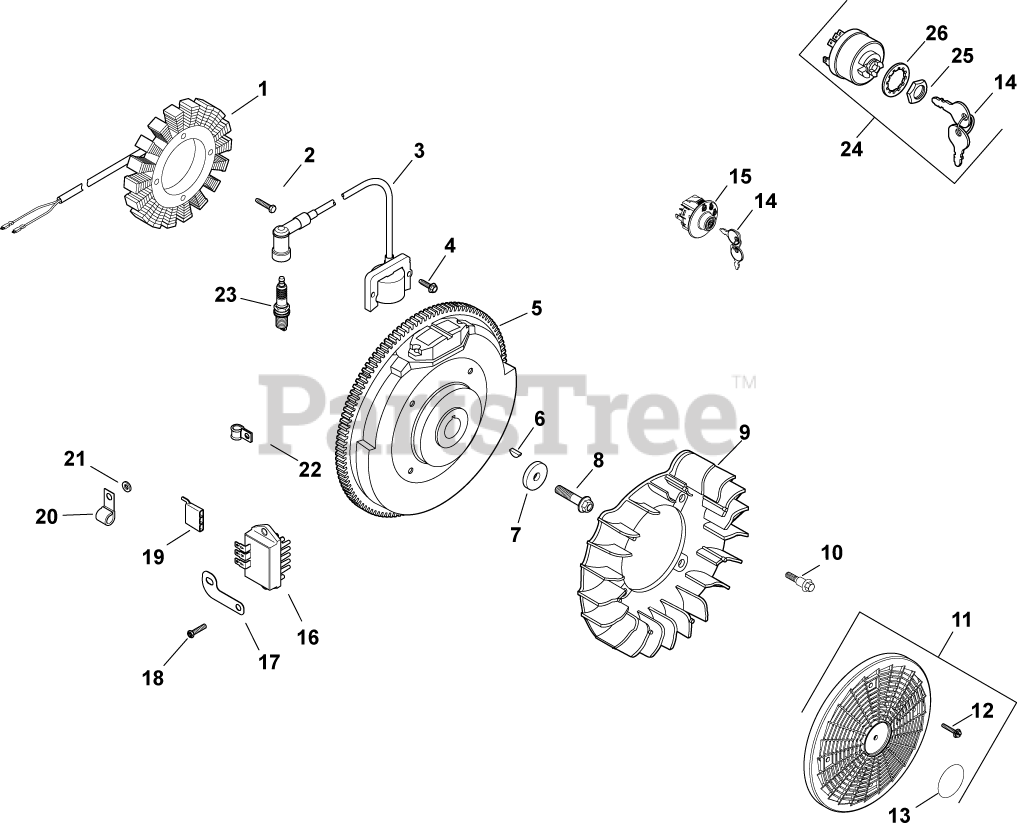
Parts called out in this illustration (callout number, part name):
1	KIT, 15 / 20 AMP STATOR
2	SCREW, THD FROM M5X0.8X30
3	KIT, MODULE IGNTN (CDI FIXED)
4	SCREW, FLG THD FRM M5X.8X20-(#25086399S)
5	FLYWHEEL ASSEMBLY
6	KEY, 3/16" X 5/8"
7	WASHER, FLAT 13/32"
8	SCREW, FLG M10X1.5X45 - (#25086361S)
9	FAN USE 24 755 253-S
10	BOLT, SHOULDER
11	KIT, GRASS SCREEN
12	SCREW, FLG SEMS M4X.7X25
13	DECAL, GRASS SCREEN USE 24 113 499-S
14	KEY, SET OF 2
15	KIT, KEY SWITCH (SNAP-IN)
16	REGULATOR, RECTIFIER USE 25 403 32-S
17	BRACKET, GROUND STRAP USE 24 518 12-S
18	SCREW, HEX FLANGE HI-LO
19	CONNECTOR
20	CLIP, CABLE
21	WASHER, FLAT 1/4" (O.D. 1/2")
23	PLUG, SPARK (PRO SERIES)
24	SWITCH ASSY, KEY (KM)-USE 25 099 32-S
25	NUT, KEY SWITCH
26	WASHER, INTERNAL TOOTH
2551834-S	LEAD, 20/25 AMP B+
